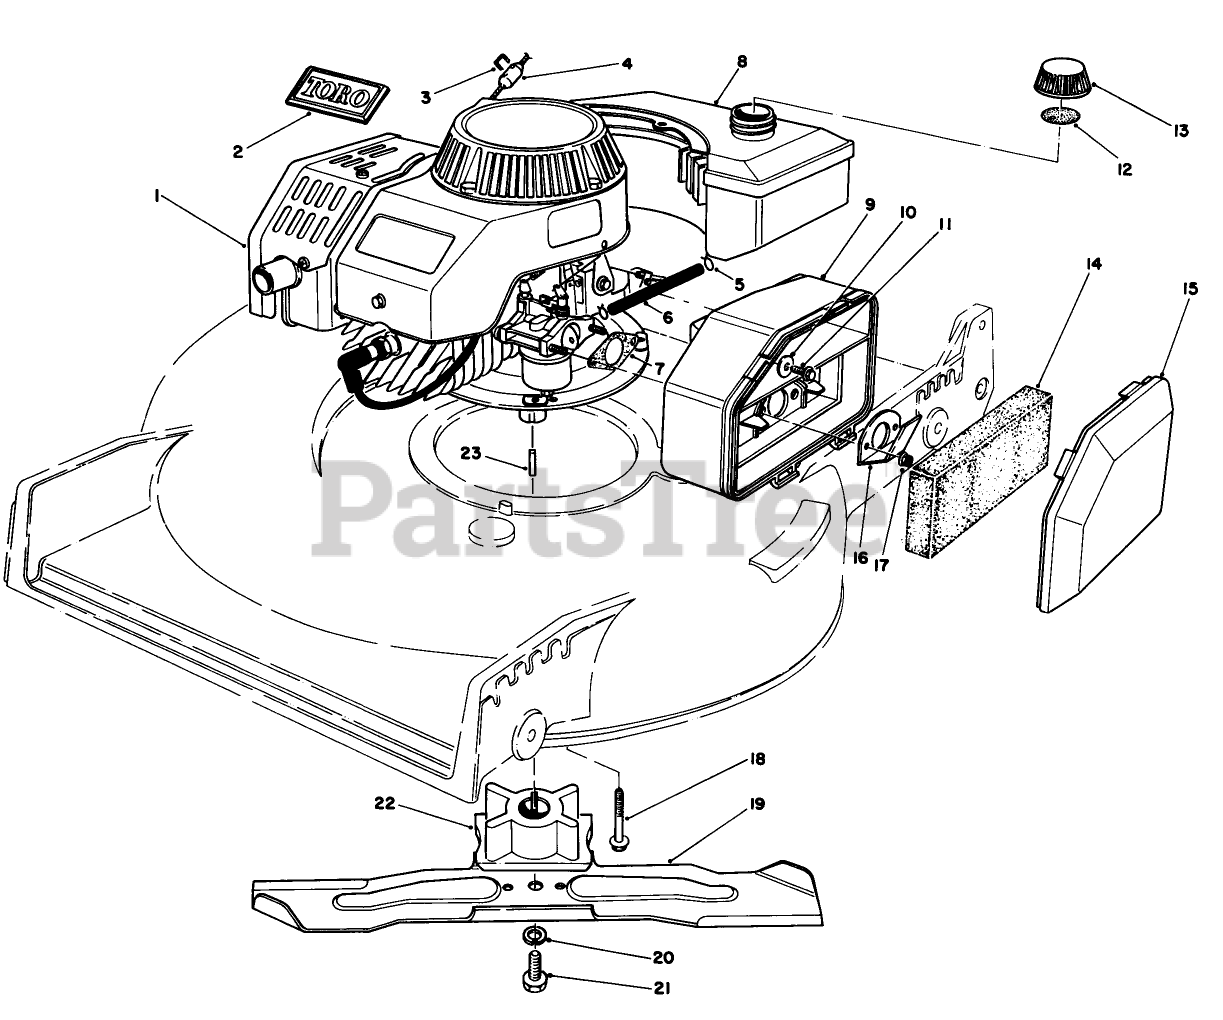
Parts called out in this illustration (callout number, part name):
3	Staple
4	STOP-ROPE
5	CLAMP-HOSE
6	FUEL LINE
7	GASKET-AIR CLEANER
9	AIR CLEANER
10	WASHER-FLAT
11	SCREW-HH
12	GAS CAP GASKET
13	GAS CAP ASM 50:1
14	FILTER
16	SPIT BACK DEFLECTOR
18	SCREW-HHF
20	WASHER-LOCK
21	SCREW-BLADE
23	KEY-SQUARE
